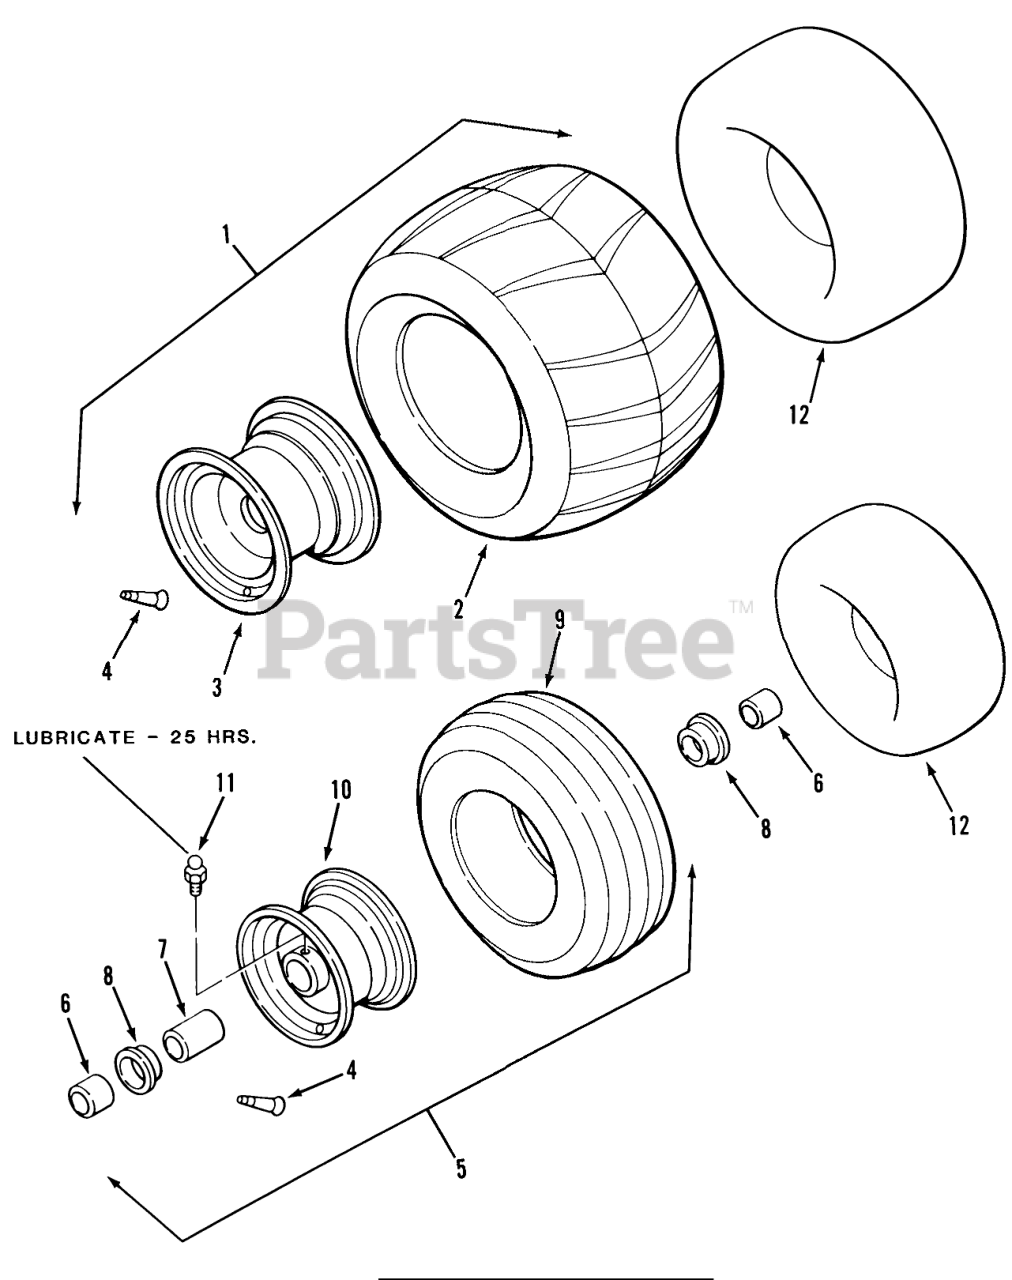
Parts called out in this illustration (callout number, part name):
1	Rear Wheel and Tire 21 x 12.00-8-Knobby (Includes items 2, 3 & 4)
2	Rear Tire-Knobby
3	WHEEL PR SLVR 10238K
4	VALVE
5	Front Wheel and Tire Ass-y (Includes items 7, 8, 9 & 10)
6	Front Wheel Spacer 5/8 x 1
7	SPACER FRT WHEEL INN
8	BEARING BALL
9	Front Tire 13 x 5.00-6
10	WHEEL FT SLUV 10239K
11	Zerk
12	INNER TUBE
